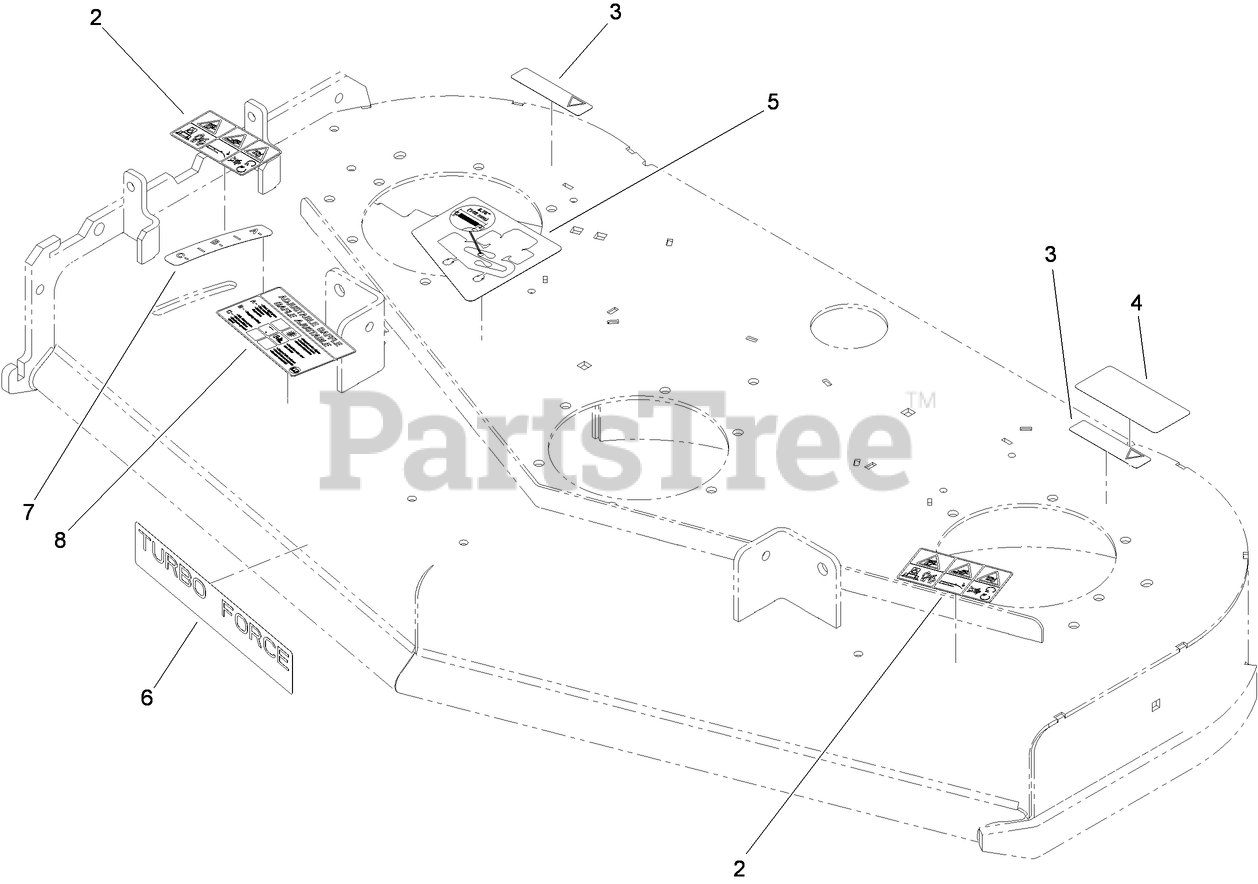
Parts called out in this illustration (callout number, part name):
2	DECAL-DANGER
3	DECAL-WARNING
4	DECAL-TORQUE, BLADE BOLT
5	DECAL-BELT ROUTING, CE
7	DECAL-SETTING, BAFFLE
8	DECAL-ADJUSTMENT, BAFFLE
